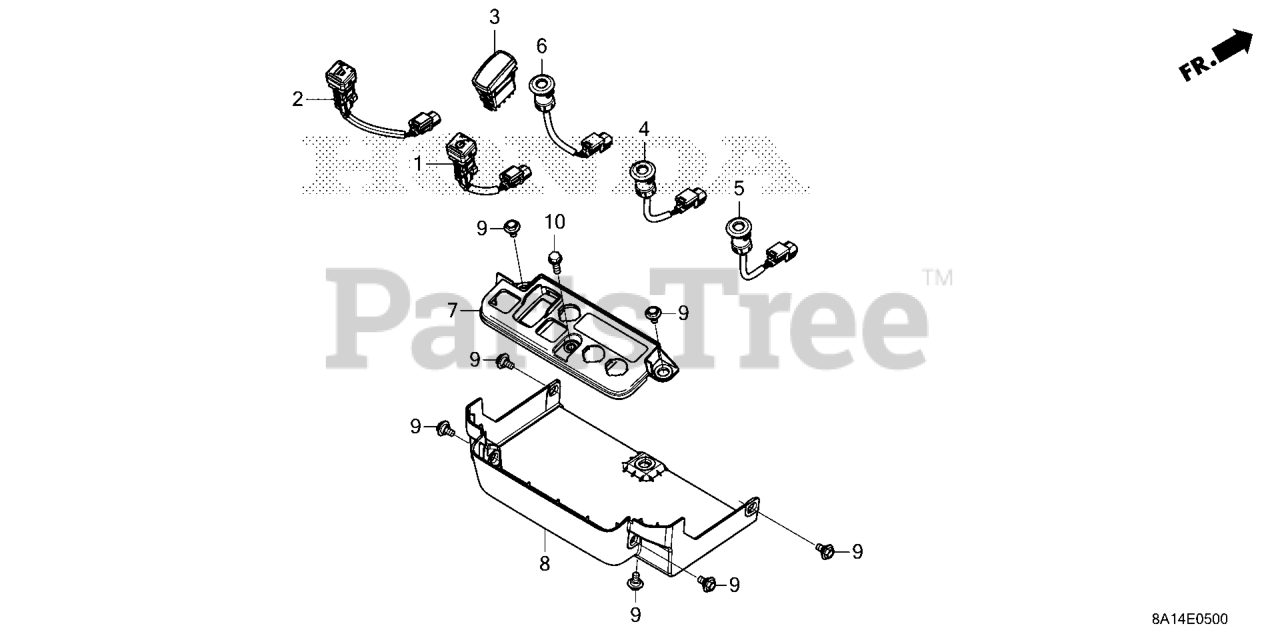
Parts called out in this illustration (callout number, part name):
1	SWITCH ASSY., POWER
2	SWITCH ASSY., SPEED
3	SWITCH ASSY., START
4	LAMP, INDICATOR
5	LAMP, INDICATOR
6	LAMP, INDICATOR
7	COVER, CONTROL *NH1*
8	COVER, PDU *NH1*
9	BOLT, SPECIAL (6X12)
10	BOLT, FLANGE (6X20)
